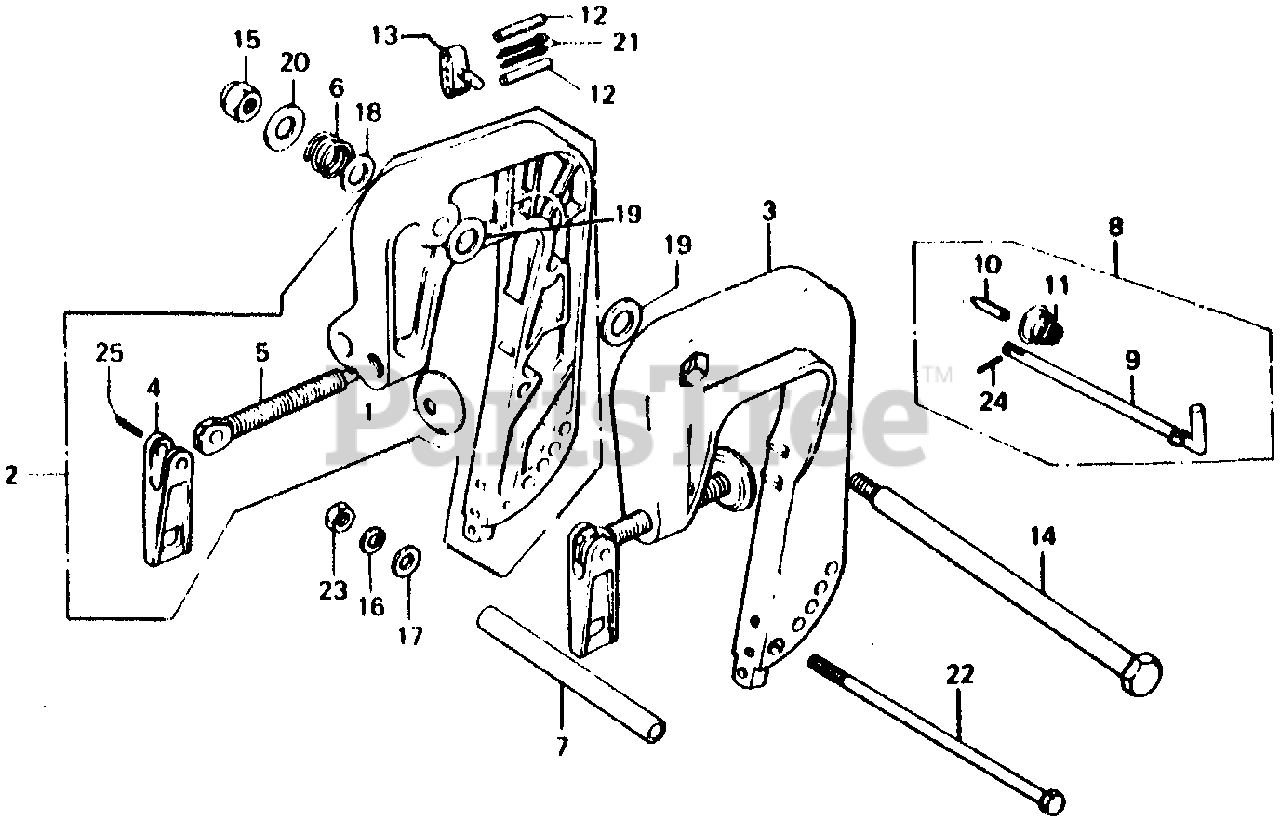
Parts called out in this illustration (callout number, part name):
1	PLATE, PUSH
2	BRACKET, R. STERN *B9* (ATLANTIS BLUE) (NOT AVAILABLE)
3	BRACKET, L. STERN *B9* (ATLANTIS BLUE) (NOT AVAILABLE)
4	GRIP, CLAMP *B9* (ATLANTIS BLUE) (NOT AVAILABLE)
5	SCREW, CLAMP
6	SPRING, TILT
7	COLLAR, DISTANCE (6MM) (NOT AVAILABLE)
8	ROD, ADJUSTING (N/A: SEE COMPONENTS)
9	ROD, ADJUSTING (NOT AVAILABLE)
10	STOPPER, ROD (NOT AVAILABLE)
11	SPRING, ADJUSTING ROD
12	PIN, SHEAR
13	HOLDER, PARTS
14	BOLT, TILTING
15	NUT, SELF-LOCK (8MM)
16	WASHER, SPRING (6MM)
17	WASHER, PLAIN (6MM)
18	WASHER, PLAIN (10MM)
19	WASHER (10MM)
20	WASHER (8MM)
21	PIN, SPLIT (3MM)
22	BOLT, HEX. (6X160)
23	NUT, HEX. (6MM)
24	PIN, SPRING (2X8)
25	PIN, SPRING (4X14)
